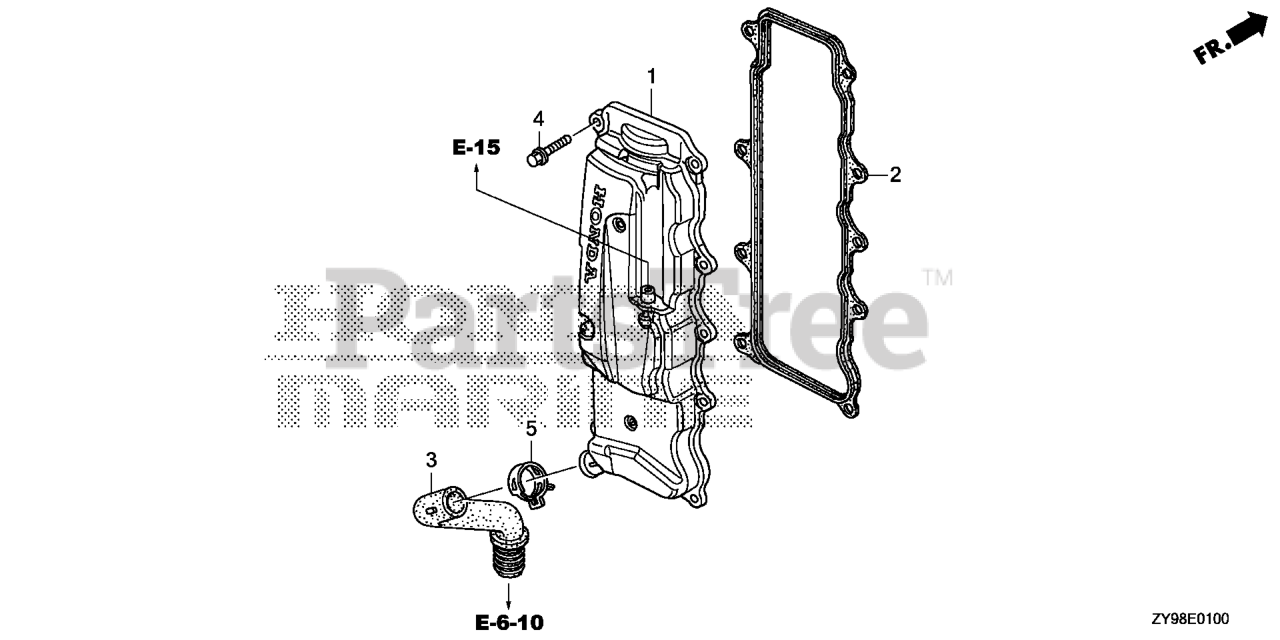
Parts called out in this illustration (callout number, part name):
1	COVER, CYLINDER HEAD
2	GASKET, HEAD COVER
4	BOLT, FLANGE (6X22)
5	CLAMP, TUBE (D29)
